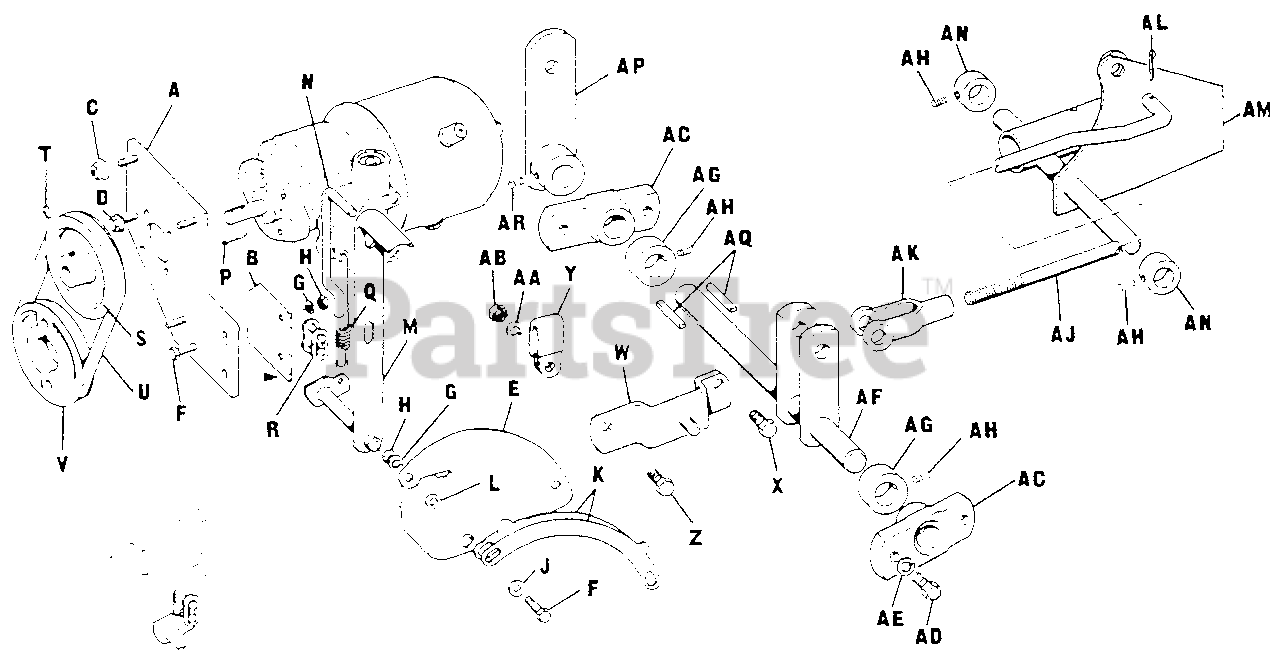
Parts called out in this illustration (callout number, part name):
A	Pump Support Assembly (157587)
B	Angle Bracket
C	Hex. Nut, Whiz Lock, 5/16"-18
D	Hex. Cap Screw, Whiz Lock, 1/4"-20 x 3/4" (709002)
F	Hex Cap Screw 1/4"-20 x 3/4"
G	Lock Washer, 1/4"
H	Full Hex. Nut, 1/4"-20
J	Plains Washer, 1/4"
K	Stop Plate
M	Lever Assembly
N	Latch Rod
P	Cotter Pin 3/32" x 5/8"
R	Connecting Link
S	Pump Pulley
T	Set Screw, 5/16"-18 x 5/16"
V	Drivel Pulley (Used On 2010 only)
W	Pivot Bar Assembly
X	Hex. Cap Screw, 5/16"-18 x 1"
Y	Hose Clamp
Z	Hex Cap Screw, 1/4"-20 x 1"
AA	Lock Washer, 1/4"
AB	Full Hex. Nut, 1/4"-20
AC	Lift Lever Bearing
AD	Hex. Cap Screw, 3/8"-16 x 7/8"
AE	Lock Washer, 3/8"
AF	Lift Shaft Assembly
AG	Set Collar
AH	Set Screw, 5/16"-18 x 5/16"
AK	Adj. Yoke End (157301)
AL	Cotter Pin, 1/8" Dia. x 1"
AM	Tiller Lift Assembly
AN	Set Collar
AP	Front Lift Lever Assembly
AR	Set Screw. 5/16"-18 x 1/4"
